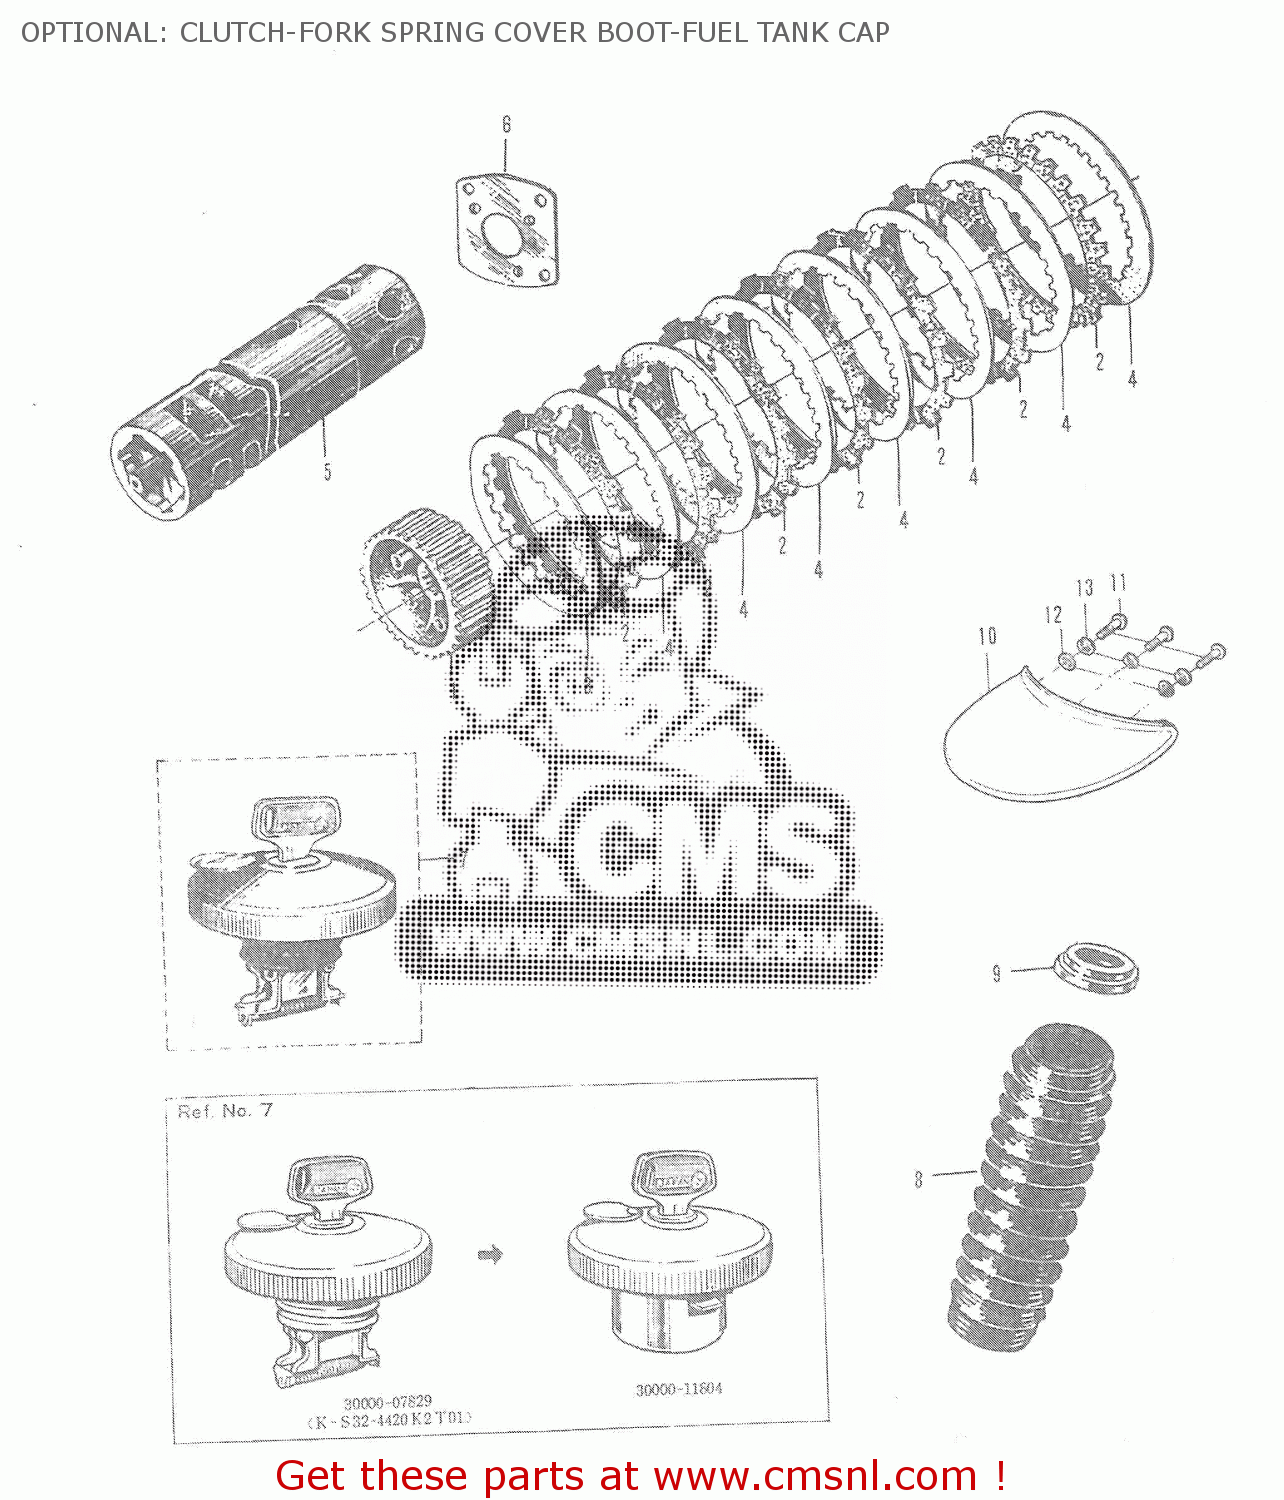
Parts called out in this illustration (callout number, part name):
1	CLUTCH SLEEVE HUB
2	CLUTCH CORK PLATE
3	CLUTCH STEEL PLATE
4	CLUTCH STEEL PLATE
5	GEAR SHIFTING CAM COMP
6	GEAR SHIFTING CAM RETAINER
7	FUEL TANK CAP
8	BOOT,SPRING COVER
9	BAND,FRONT FORK COVER
10	REAR FENDER EXTENSION
11	HEXAGON BOLT
12	LOCK WASHER
13	FLAT WASHER
